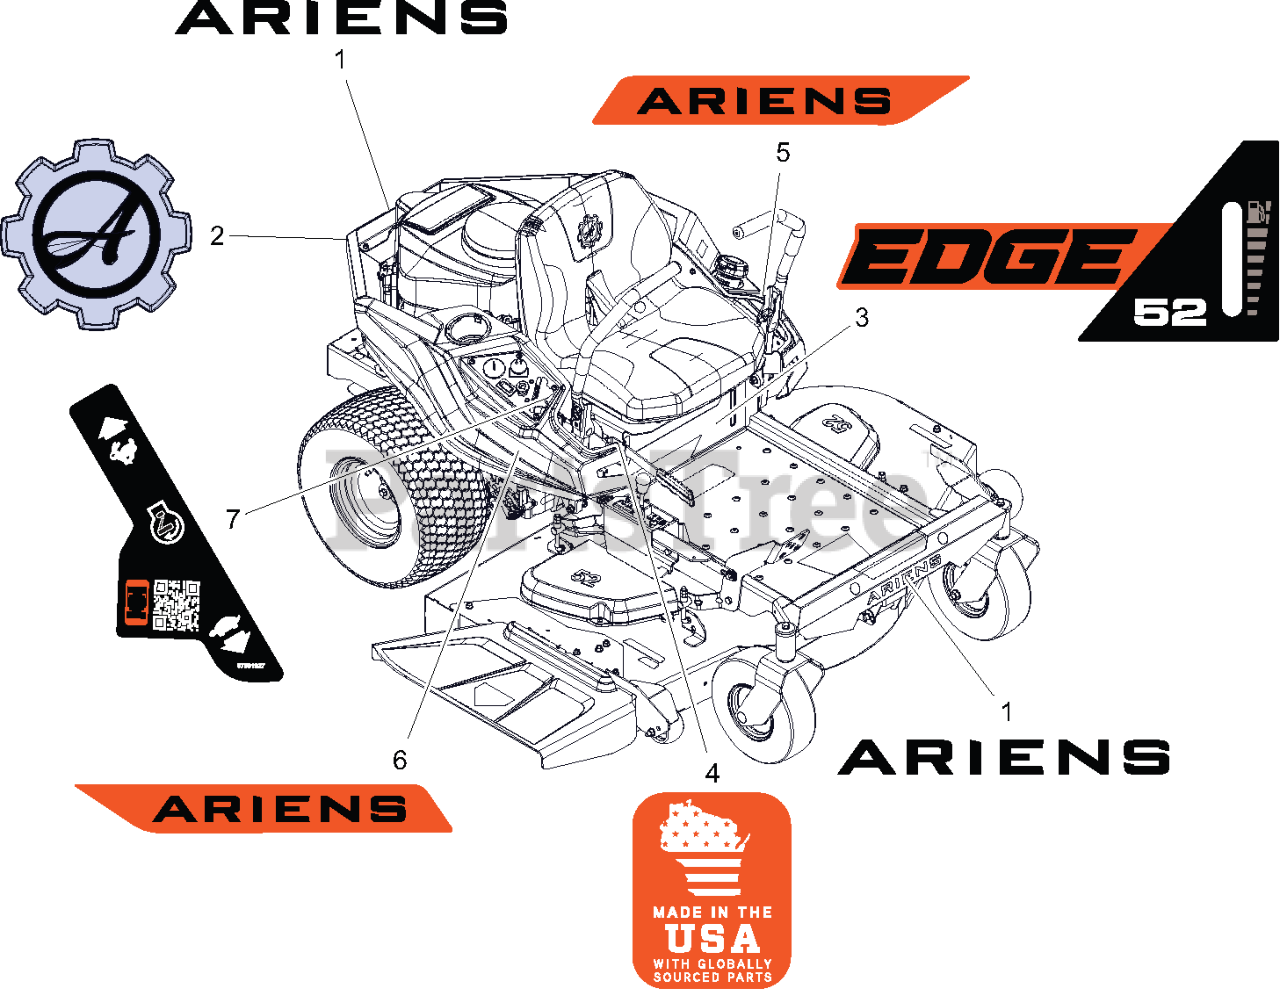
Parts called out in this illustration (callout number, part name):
1	DECAL- ARIENS 9.625" BLACK
2	DECAL- ARIENS GEAR BADGE
3	DECAL- EDGE 52 KICKPLATE
4	DECAL- MADE IN USA
5	DECAL- ARIENS (FENDER LH)
6	DECAL- ARIENS (FENDER RH)
7	DECAL- TROTTLE CONTROL
